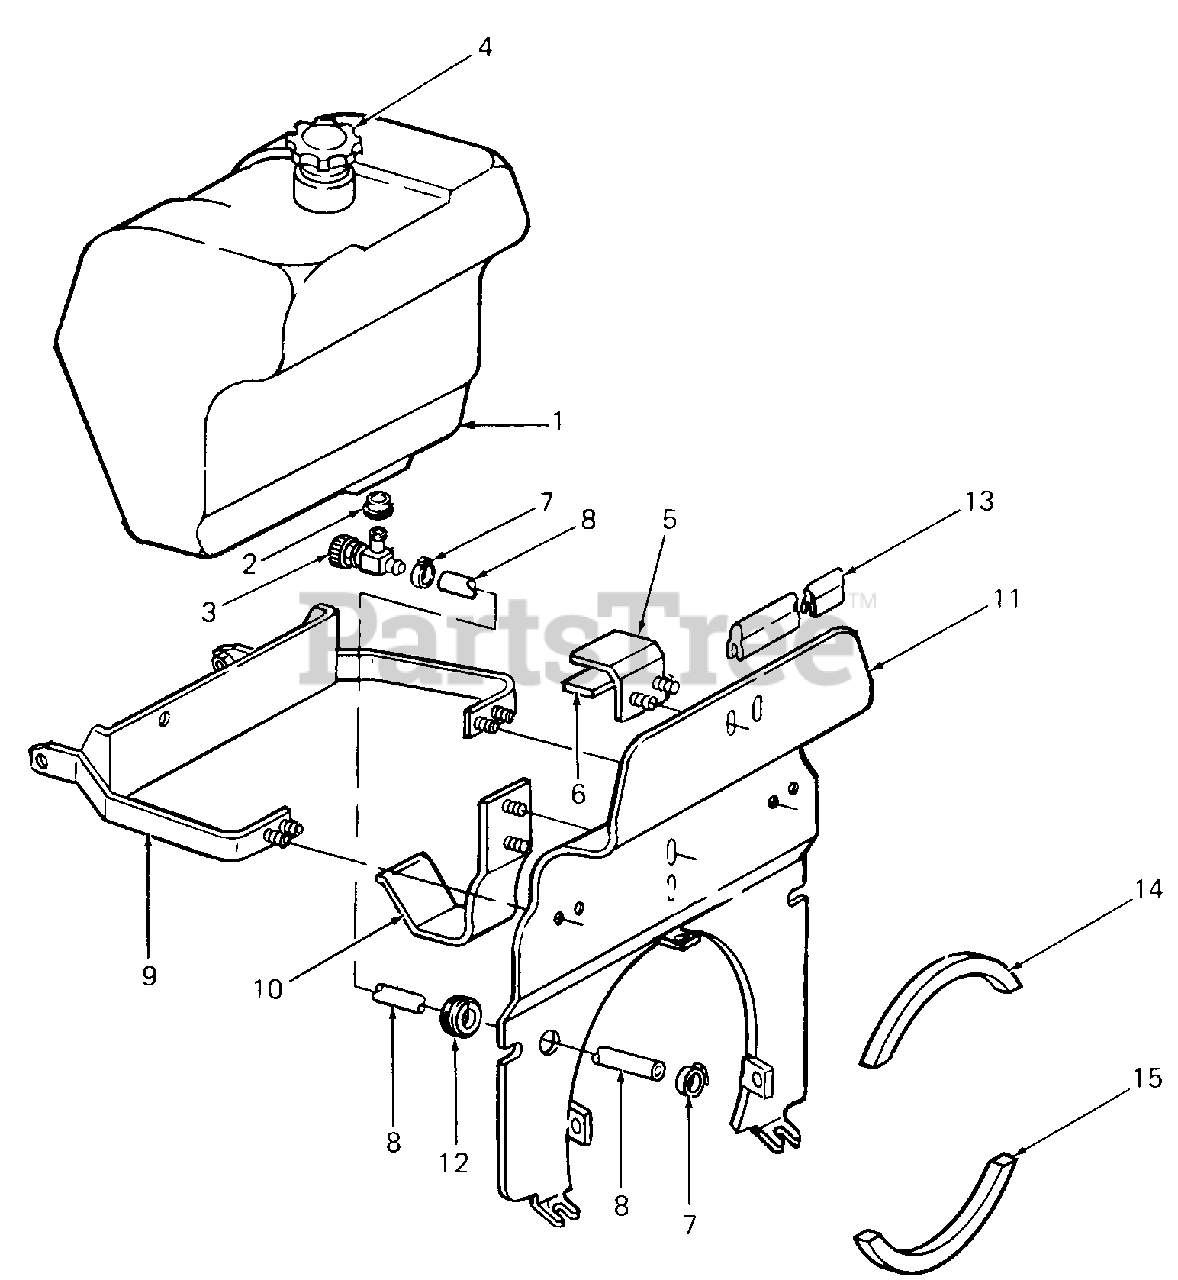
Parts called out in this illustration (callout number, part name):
1	Tank, Fuel
2	Bushing
3	Valve, Shut-off w/Screen
4	Gauge, Fuel Cap
5	Clamp, Fuel Tank
6	Pad, Fuel Tank Adhesive, Loctite, #495
7	Clamp, Hose
8	Line, Fuel - 14 in. Lg
9	Support, Fuel Tank
10	Support, Fuel Tank Bottom
11	Deflector, Heat
13	Seal, Heat Baffle, 56 in. Lg
14	Strip, Foam Gasket Sealing, 27 in. Lg
15	Strip, Foam Gasket Sealing, 17 in. Lg
